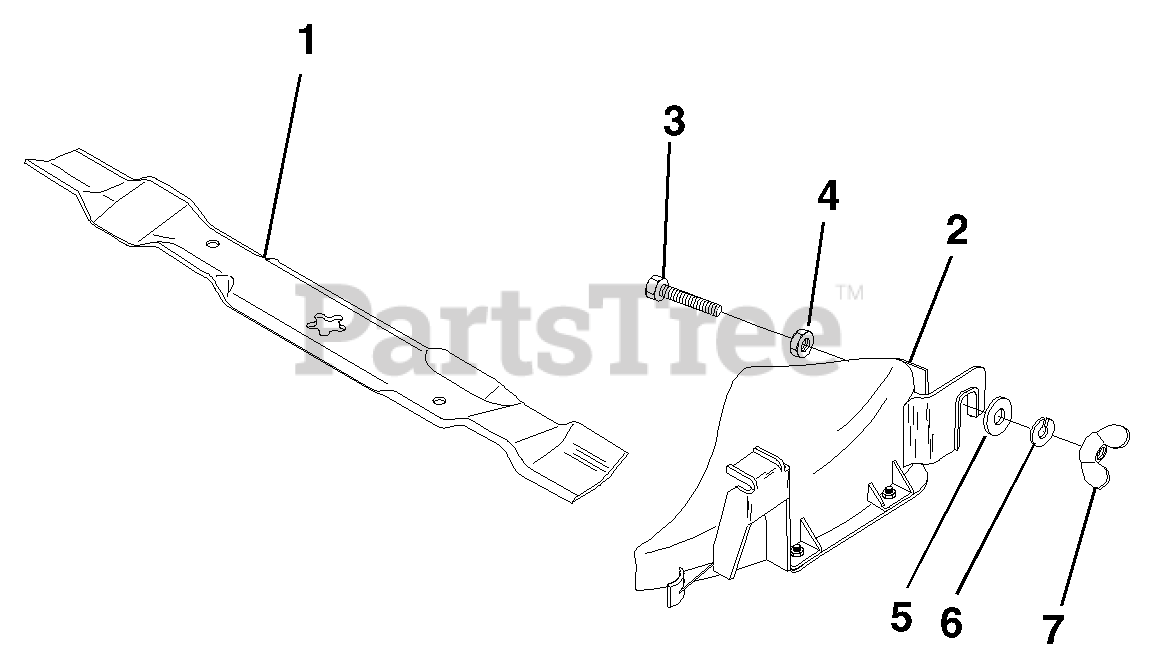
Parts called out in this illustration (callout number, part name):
1	Blade, Mulching
2	Cover, Mulcher
3	Bolt, Hex 3/8-16 x 1-1/4
4	Locknut 3/8-16
5	Washer 13/32 x 1-1/4 x 16 Ga.
6	Washer, Lock 3/8
